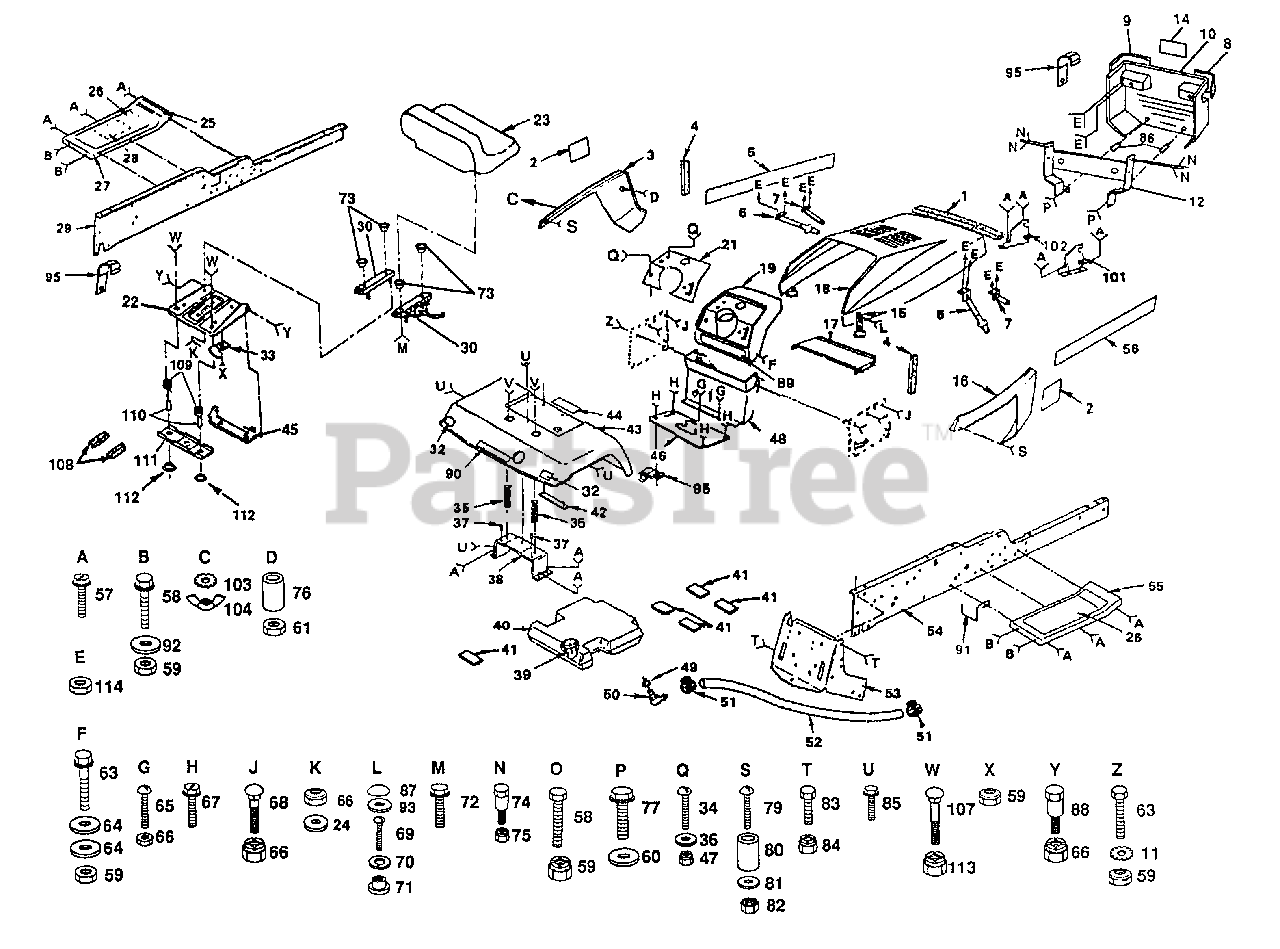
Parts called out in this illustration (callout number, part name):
1	Strip, Foam
2	Decal-Hood, GTK 18
3	Panel-Side, L.H.
4	Strip-Foam
5	Decal-Hood, L.H.
6	Strap Assembly-Hinge, Rear
7	Strap Assembly-Hinge, Front
8	Lens R.H.
9	Lens L.H.
10	Grill Assembly
11	Washer, Lock Ext. Tooth 3/8
12	Support-Grill, R.H.
14	Decal, Grill, Husqvarna
15	Latch-Hood
16	Panel-Side, RH.
17	Support-Battery
18	Hood
19	Dashboard
21	Dashplate
23	Seat
24	Washer 11/32 x 1 x 10 Ga.
25	Decal-Clutch/Brake
26	Pad-Footrest
27	Footrest-L.H.
28	Decal-Drive Belt Schematic
29	Rail-Frame-L.H.
30	Slide, Seat Set
32	Reflector-Taillight
33	Clip-Insulated
34	Screw, Mach. Hd. 5/16 - 18 x 3/4
35	Spring-Compression
36	Washer, 11/32 x 11/16 x 16 Ga
38	Bracket-Fender
39	Cap-Fuel
41	Pad-Spacer
42	Strap-Fender
44	Decal-Caution
45	Bracket-Pivot, Seat
46	Cover, Shift-Gate
47	Nut, Keps 5/16 - 18
48	Dash Assembly
50	Stem-Tank Fuel
51	Clamp-Hose
52	Fuel Line
53	Drawbar
54	Rail-Frame-RH
55	Footrest-RH
56	Decal-Hood RH
57	Screw-Hex Washer Thread Rolling 3/8-16 x 3/4
58	Bolt-Hex 3/8-16 x 3/4
59	Nut-Lock 3/8-16
60	Washer 9/32 x 3/4 x 16 Ga
61	Nut-Hex 1/4-20
63	Bolt-Hex 3/8-16 x 1
64	Washer 13/32 x 13/16 x 16 Ga.
65	Screw-Mach, Cr Thrd. 5/16 - 18 x 3/4
66	Nut-Crownlock 5/16-18
67	Screw-Hex Washer Thrd Cutting 1/4-20 x 1/2
68	Bolt-Carriage 5/16-18 x 3/4
69	Screw-Cr. Pan. Mach. No. 10-24 x 1/2
70	Washer, Lock No. 10
71	Nut-Weld
72	Screw-Hex 5/16 - 18 x 1
74	Bolt-Shoulder 1/4-20
75	Nut-Crownlock 1/4-20
77	Bolt, Fin Hex 1/4 - 20 x 1 1/2
79	Screw-Mach Cr. Pan No. 10-24 x 1-1/4
80	Spacer-Split No. 10 x 3/4
81	Washer 7/32 x 1/2 x 18 Ga.
82	Nut-Keps No 10-24
83	Bolt-Hex 7/16-14 x 1
84	Nut-Lock 7/16-14
85	Screw-Hex Washer Thread Rolling 3/8 x 16 x 1/2
88	Bolt-Shoulder
89	Decal-Caution
90	Decal-Fender
91	Retainer, Belt, Lower
92	Washer 13/32 x 13/16 x 17 Ga.
93	Washer, Snap Cap
95	Clip, Insulated
101	Bracket Assy Pivot Frame R.H.
102	Bracket Assy Pivot Frame L.H.
103	Washer-Lock 1/4-20
104	Nut Wing 1/4-20
106	Washer, 13/32 x 1 x 14 Ga.
107	Bolt-Carr, 1/4-20 x 1-1/4
108	Foam Strip
109	Spring, Compression
110	Spacer, Slit
111	Bracket, Switch Mount
112	Bushing, Snap
113	Nut-Flange Lock 1/4-20
114	Nut-Hex, 1/4-20
